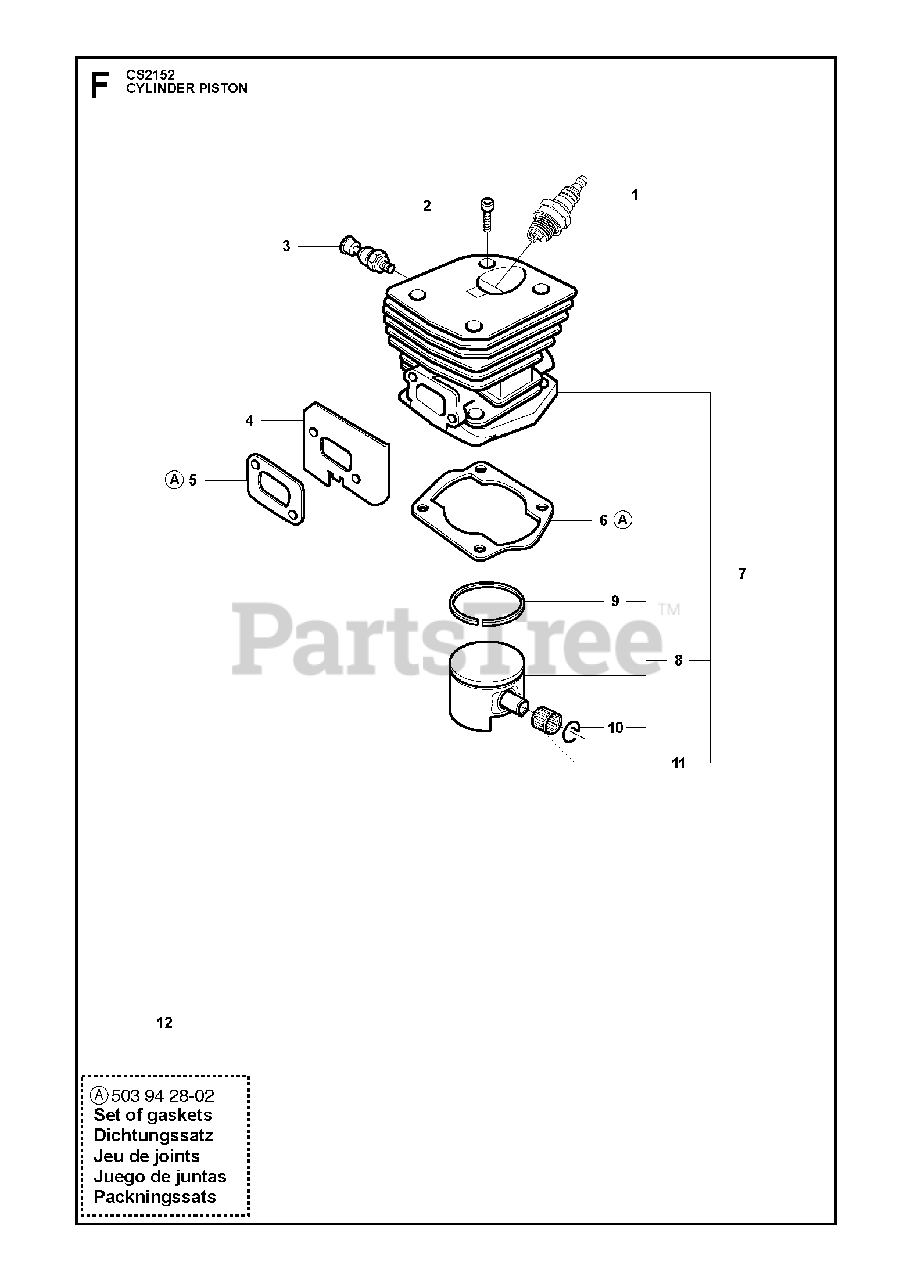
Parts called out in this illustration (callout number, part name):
1	SPARK PLUG RCJ7Y
2	SCREW MC6S 5X25
3	DECOMPRESSION VALVE
5	GASKET
6	GASKET
7	CYLINDER ASSY
8	PISTON
9	%PISTON RING
10	LOCKING RING
11	RP SUPPORT BUSHING
12	GASKET SET
